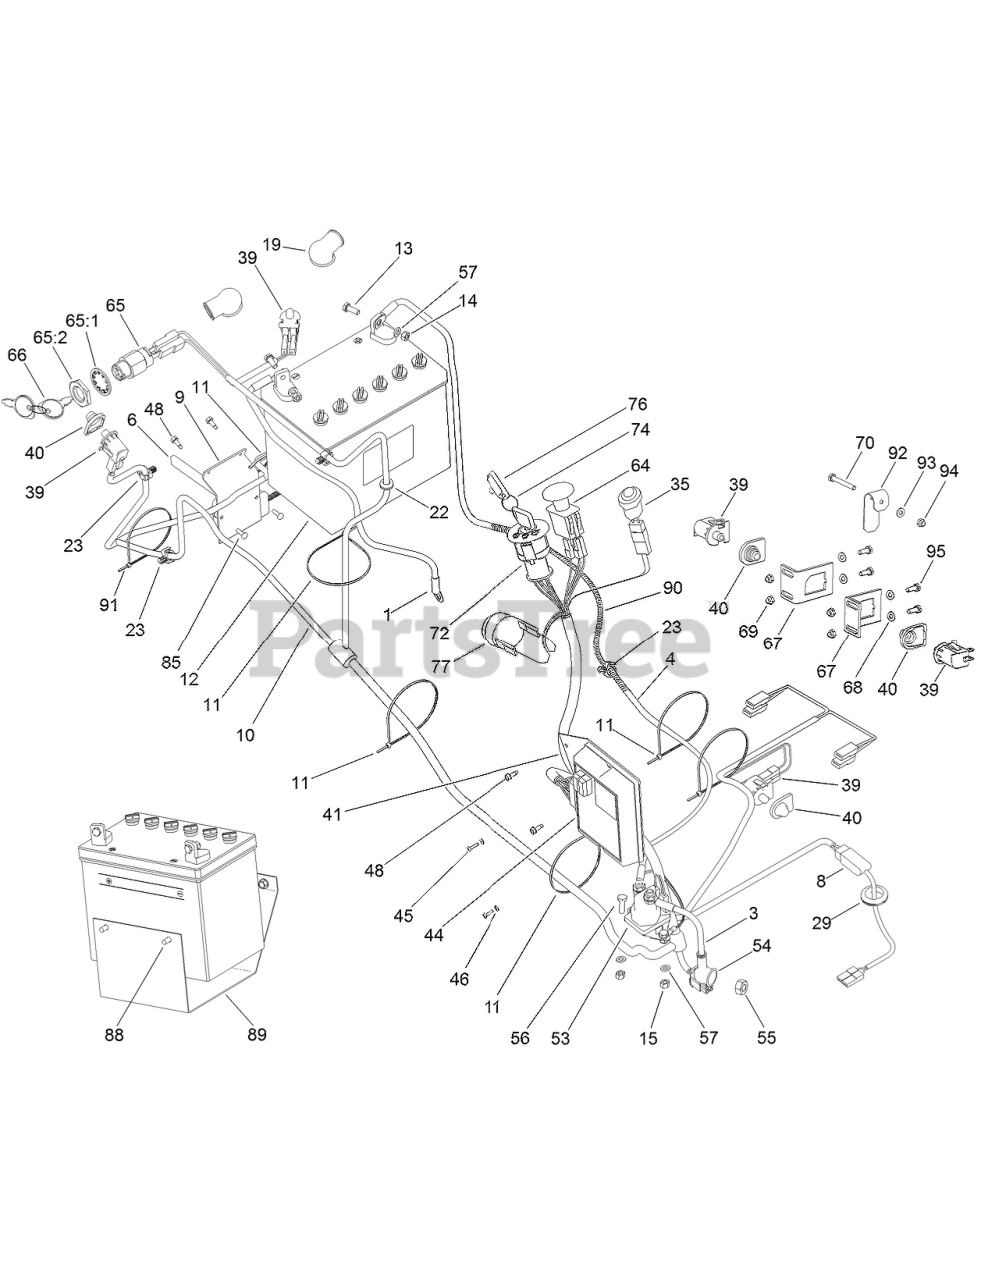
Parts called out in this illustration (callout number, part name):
1	CABLE-BATTERY, NEGATIVE
3	LEAD-STARTER, ELECTRIC
4	CABLE-BATTERY, POSITIVE
6	SWITCH-OMRON
8	HARNESS-CLUTCH
9	BRACKET-SWITCH
10	HARNESS-WIRING
11	Tie-Cable
12	BATTERY
13	SCREW-HH
14	NUT-HEX
15	NUT-LOCK
19	BOOT-RUBBER
22	BUSHING
23	CLIP-SNAP
29	BUSHING
35	LAMP-INDICATOR
39	SWITCH-DELTA
40	COVER-PROTECTIVE
41	BRACKET-SUPPORT, MODULE
44	MODULE-CONTROL
46	WASHER
48	SCREW-TAP
53	Solenoid
54	BOOT-RUBBER
55	NUT-HHF
56	SCREW-HH
57	WASHER
64	SWITCH-PTO
65	STARTER SWITCH ASM
65:1	WASHER-TOOTH, INTERNAL
65:2	NUT-HH
66	KEY-IGNITION
67	HOLDER-SWITCH
68	WASHER
69	NUT-LOCK
70	SCREW-HEX
72	SWITCH-IGNITION
76	KEY-IGNITION
77	BUZZER
85	Screw
89	HOLDER-BATTERY
90	Protection-Cable
91	TIE-CABLE
92	LEVER-SPRING
93	WASHER
94	NUT-HEX
